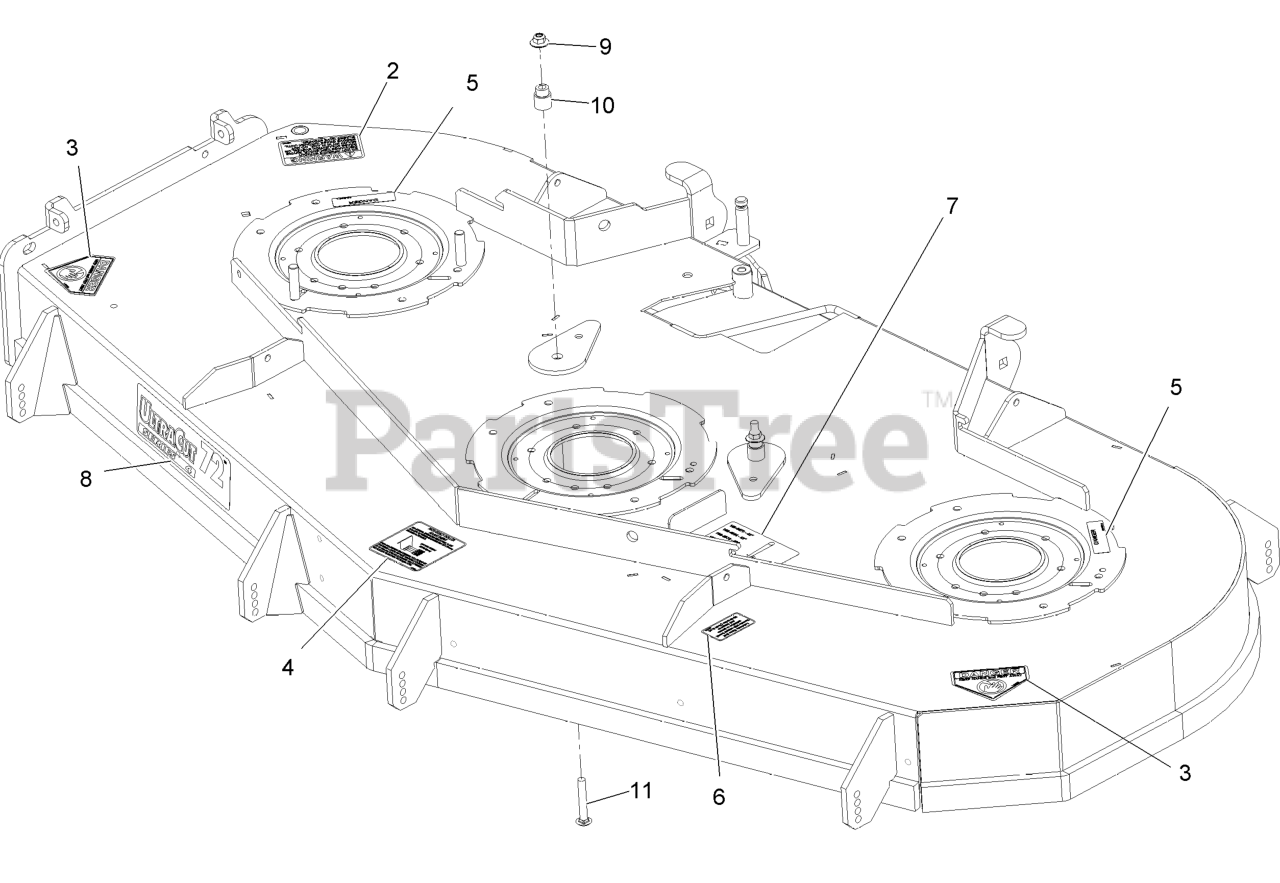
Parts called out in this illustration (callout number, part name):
2	DECAL-WARNING, DISCHARGE
3	DECAL-DANGER
4	DECAL,ANTISCALP
5	DECAL-COVER, MISSING
6	DECAL,BOLT TORQUE
7	DECAL,BELT ROUTING
8	DECAL,ULTRACUT 72 SERIES
9	Nut-Nyloc 3/8-16 Flg
10	BUSHING-IDLER
11	SCREW-CARR
